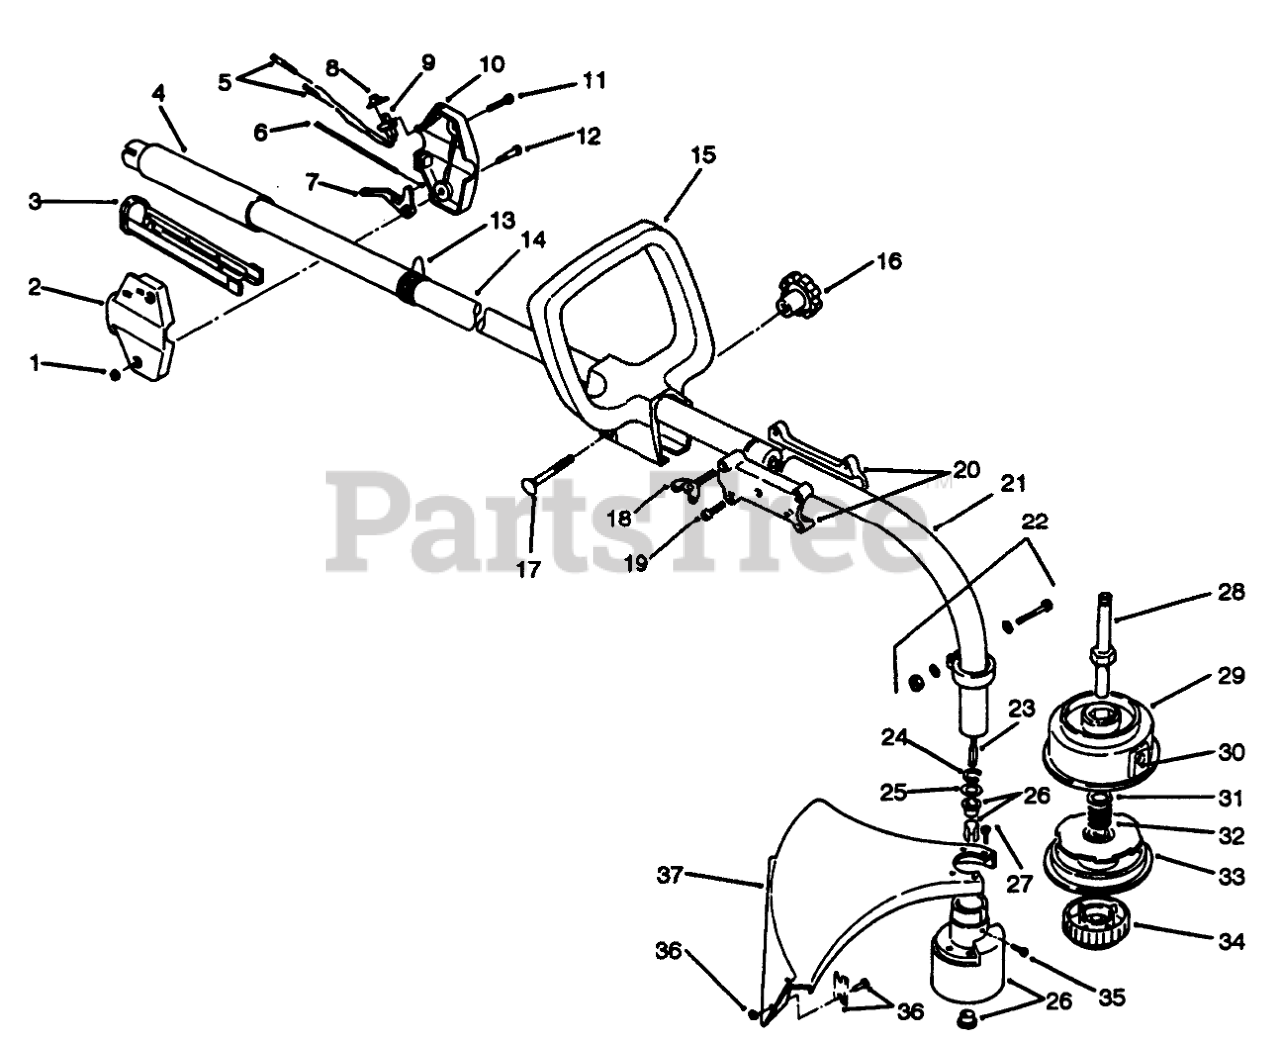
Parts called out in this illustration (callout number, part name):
1	NUT-LOCK, NI
2	RH HOUSING
3	TROUGH 1"
4	GRIP - RUBBER
5	LEAD WIRE ASM
6	THROTTLE CABLE
7	THROTTLE LEVER
8	SWITCH COVER
9	SWITCH
10	LH HOUSING
12	SCREW-SHOULDER
13	Clip-Shoulder Strap
14	UPPER DRIVE HSG ASM
15	HANDLE SECONDARY
17	BOLT-CARRIAGE
18	Adjustment knob
19	COUPLING BOLT ASM
20	Coupling-Split Boom
21	LOWER DRIVE HSG ASM
22	CLAMP ASM - UPPER
23	Drive Shaft
24	RETAINING RING
25	WASHER
26	BUSHING HSG ASM
27	GUARD MTG SCREW ASM
28	Shaft-Spool
29	OUTER SPOOL EYELET ASM
30	EYELET
31	RETAINER WASHER(SET OF 10)
32	REEL - INNER
34	SMALL BUMP KNOB ASM
35	ANTI-ROTATION SCREW
36	Assy.-Blade (Incl. 2 Screws & 2 Nuts)
37	Assembly-Guard & Blade (Incl. Ref. No. 36)
